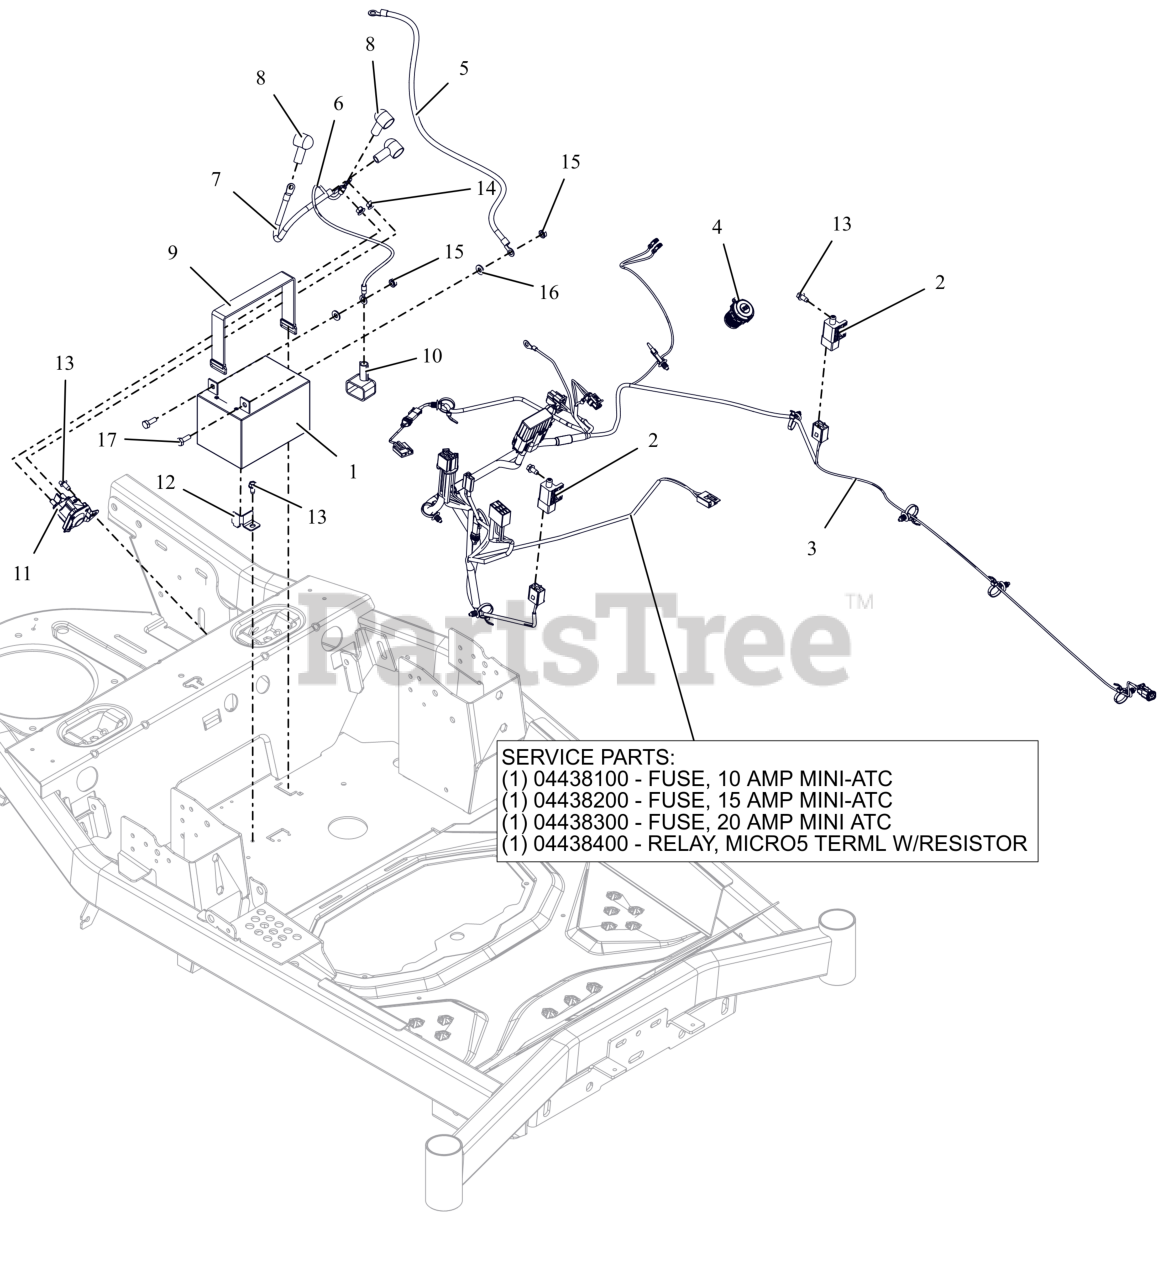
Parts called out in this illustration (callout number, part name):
1	BATTERY, 12V 12A -190CCA
2	SWITCH-BRAKE NO/NO-POST & HOLE
3	HARNESS- MAIN- IKON23
3	FUSE,10 AMP MINI-ATC
3	Fuse, 15 AMP MINI-ATC
3	FUSE,20 AMP MINI ATC
3	RELAY,MICRO5 TERML W/RESISTOR
4	USB, DUAL PORT USB-C, 12V BLK
5	CABLE-NEGATIVE BATTERY 24.00"
6	CABLE,POS W/2 1/4 RING 18.5 LG
7	CABLE, POS W/(2)1/4 RING 9.0LG
8	BOOT, EYELET TERMINAL
9	STRAP- RUBBER
10	INSULATOR
11	SOLENOID, STARTER (SEALED)
12	RETAINER, BATTERY CORNER (BLACK)
13	SCR-TAP .25-20X.50 HWH ZCC
14	NUT- M6-1.0 W/ CONICAL WASHER
15	NUT-KEPS .250-20 ZCC
16	WSHR,FLT .281X.625X.065 ZCC
17	BLT, HEX .25-20X.75 G5 ZCC
